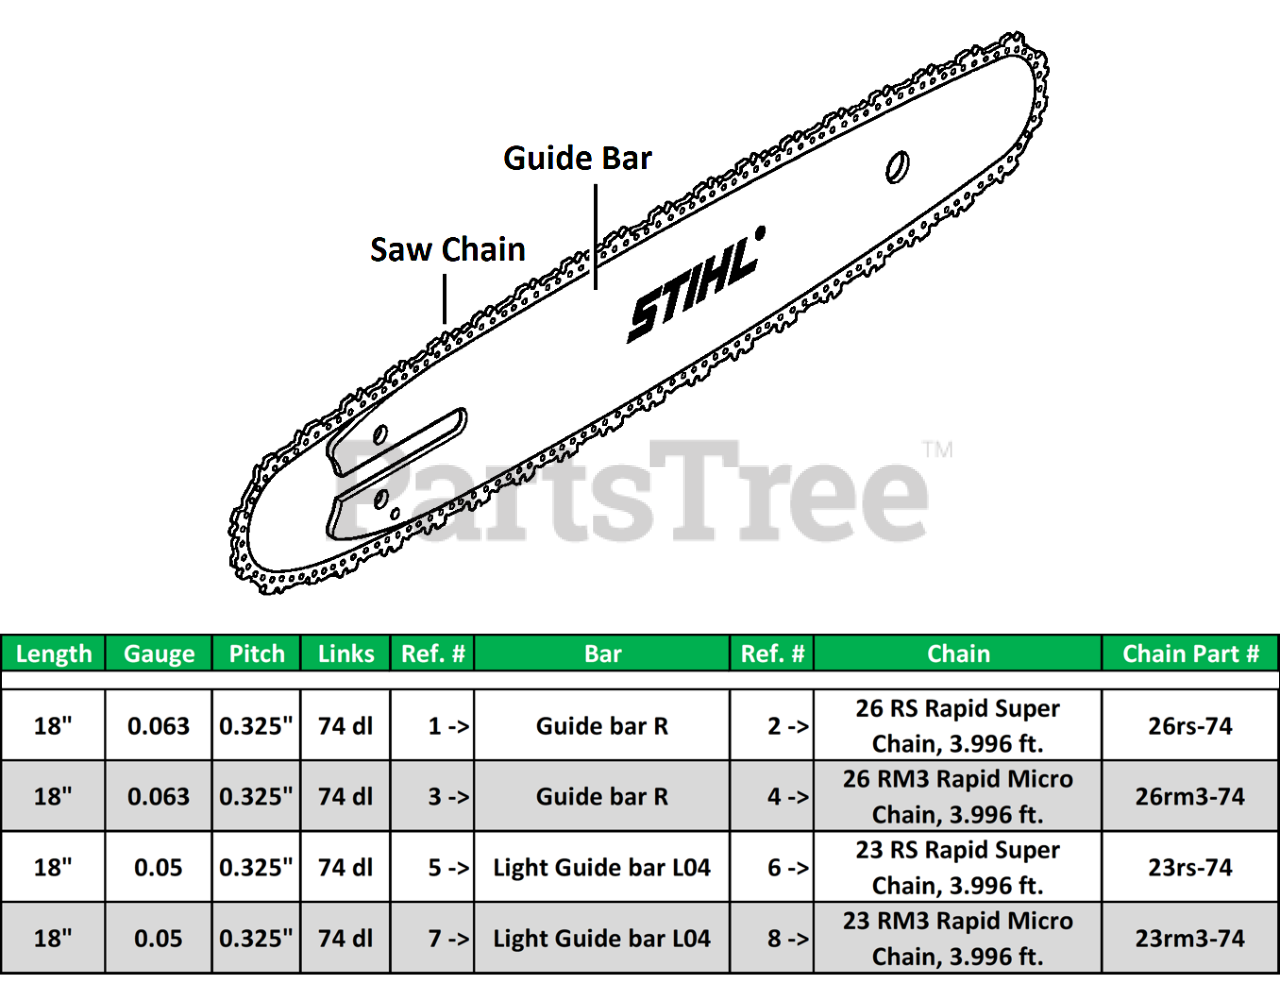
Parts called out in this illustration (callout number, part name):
1	Guide bar R 45cm/18" 1,6mm/0.063" .325"
2	26 RS Rapid Super Chain, 3.996 ft.
3	Guide bar R 45cm/18" 1,6mm/0.063" .325"
4	26 RM3 Rapid Micro Chain, 3.996 ft.
5	Guide bar L04 45cm/18" 1,3mm/0.050"
6	23 RS Rapid Super Chain, 3.996 ft.
7	Guide bar L04 45cm/18" 1,3mm/0.050"
8	23 RM3 Rapid Micro Chain, 3.996 ft.
